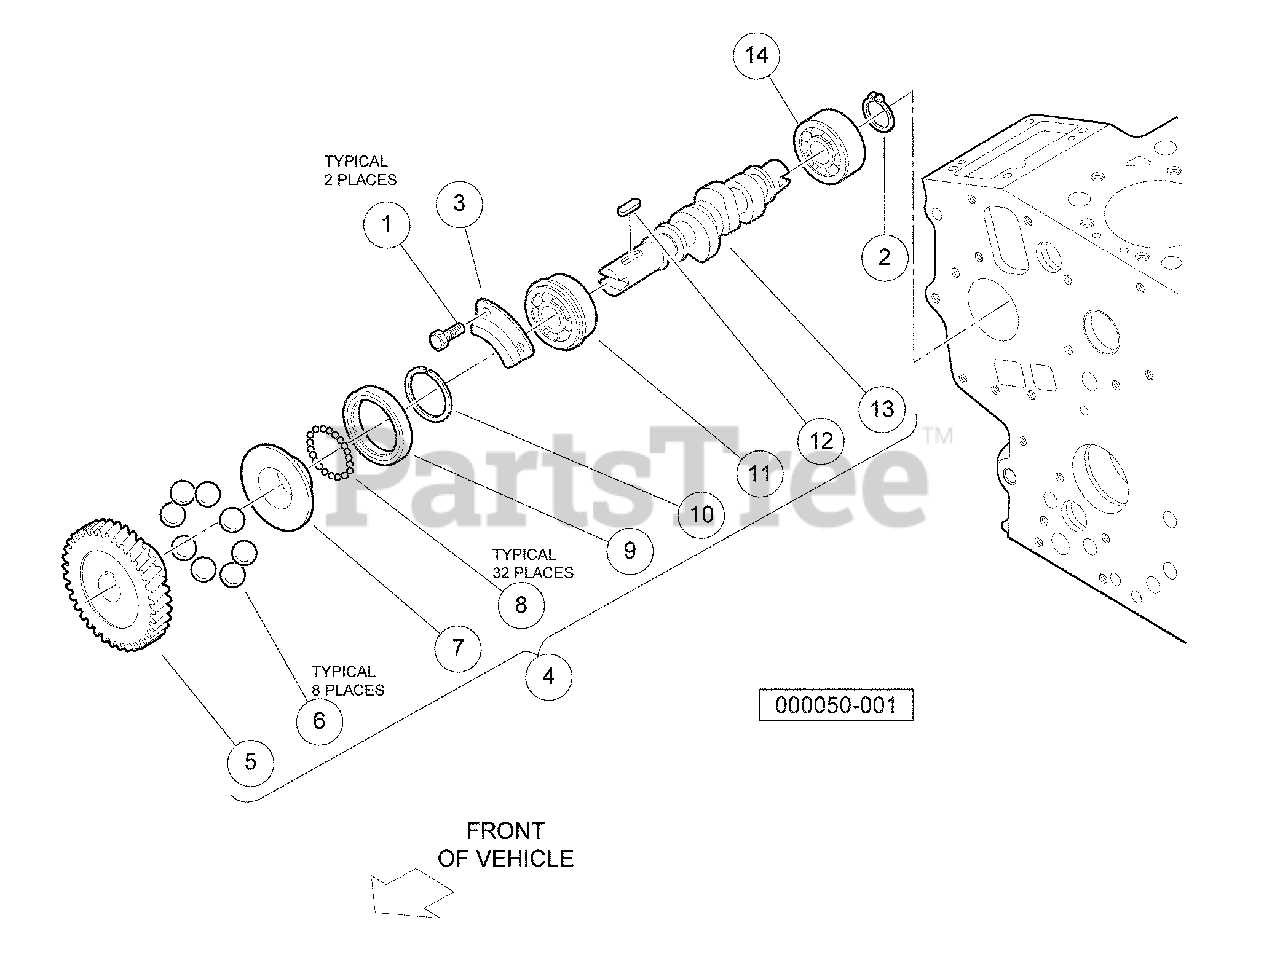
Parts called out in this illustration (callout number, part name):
1	Bolt, D722, Cam End
2	Circlip, External
3	Stopper, Fuel, C/shaft
4	Assy, Fuel Camshaft
5	Gear, Injection Pump
6	Ball, Injection Pump
7	Sleeve, Governor
8	Ball, Governor
9	Case, Governor Ball
11	Bearing, Ball
12	Key, Feather, Short Camshaft
13	Camshaft, Fuel, Short
14	Bearing, Ball
